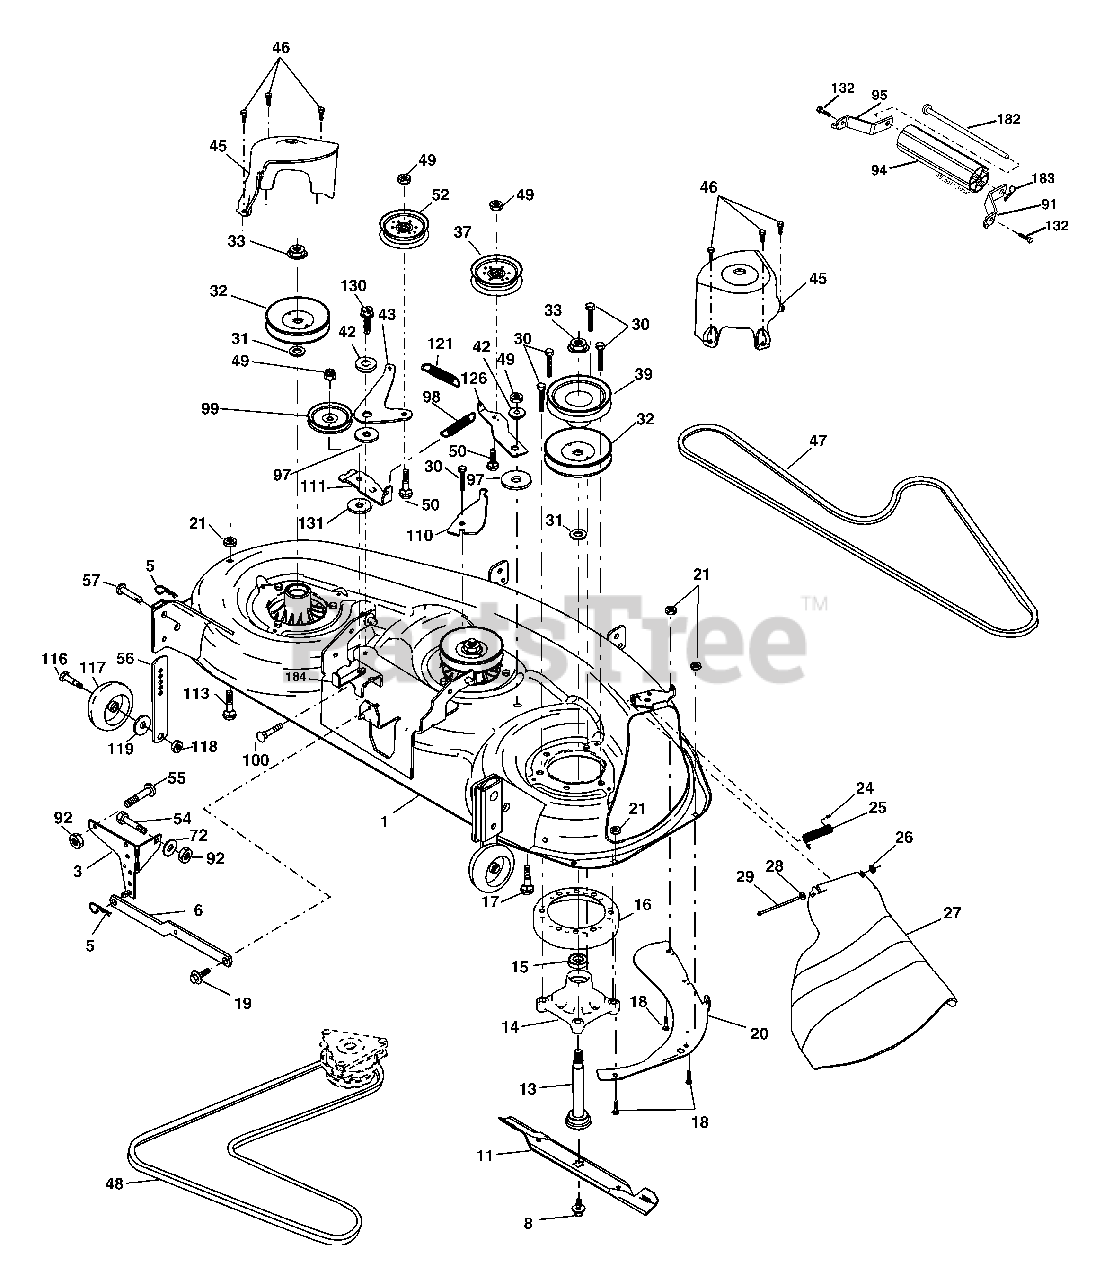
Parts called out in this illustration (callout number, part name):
1	Deck Weldment Mower 48
3	Bracket Asm., Sway Bar
5	Retainer Spring
6	Bar Sway Deck
8	Bolt, 7/16 Asm. Blade
13	Shaft Asm. Mandrel Sealed
14	Housing Mandrel 48"
15	Bearing, Ball, Mandrel
16	Stripper, Mower
17	Bolt Rdhd Sq Neck 3/8-16 x 1.25
18	Bolt, Carriage 5/16-18 x 5/8
19	Bolt, Hex Head, Shoulder 5/16-18
20	Baffle, Vortex Mower
21	Nut, Crownlock 5/16-18 unc
24	Cap, Sleeve
25	Spring, Torsion
27	Shield, Deflector Mower
28	Washer 11/32 x 5/8 x 16 Ga.
29	Rod, Hinge
30	Screw, Thdroll, Washer Head
31	Washer, Spacer Mower Vented
32	Pulley, Mandrel
33	Nut, Flg. Top Lock Cntr. 9/16
36	Washer 13/32 x 13/16 x 16 Ga.
37	Pulley, Idler, Flat
39	Pulley, Idler, Driven
42	Spacer, Retainer
43	Arm, Idler Secondary
45	Cover, Mandrel Deck
46	Screw, Thdroll. 1/4-20 x 5/8
47	V-Belt, Mower, Secondary
48	V-Belt, Mower, Primary
49	Nut, Crownlock 3/8-16 unc
50	Bolt, Carriage 3/8-16 x 1-1/2 Gr. 5
52	Pulley Idler Flat 46 Pri. Drive
54	Bolt Fin Hex 3/8-16 x 1
55	Bolt Rdhd Sqnk 3/8-16 x 1
56	Bar Pnt Adjusting Wheel Gauge
57	Pin Head Rivet
72	Washer 13/32 x 13/16 x 12
91	Bracket, Asm Noseroller, RH 48
92	Nut Lock Hex w/Ins 3/8-16
94	Roller, Nose 48"
95	Bracket, Asm Noseroller LH 48
97	Washer Hardened
98	Spring Primary Drive
99	Pulley Idler "V"
100	Bolt RDHD Sqnk 3/8-16 unc x 2
110	Arm Spring Secondary
111	Arm Spring Fixed Tension
116	Bolt, Shoulder
117	Gauge Wheel
118	Nut, Centerlock 3/8-16 unc
119	Washer 3/8 x 7/8 x 14 Ga.
121	Spring Secondary Drive
126	Arm, Idler, Primary Deck
130	Screw 3/8-16 x 1.0
131	Washer 13/32 x 1 x 6 Ga.
132	Screw 3/8-16 x 3/4
133	Bolt Rdhd Sqnk 5/16-18 unc x 3/4
182	Rod Roller Nose
183	Retainer Spring
184	Keeper Belt Idler
